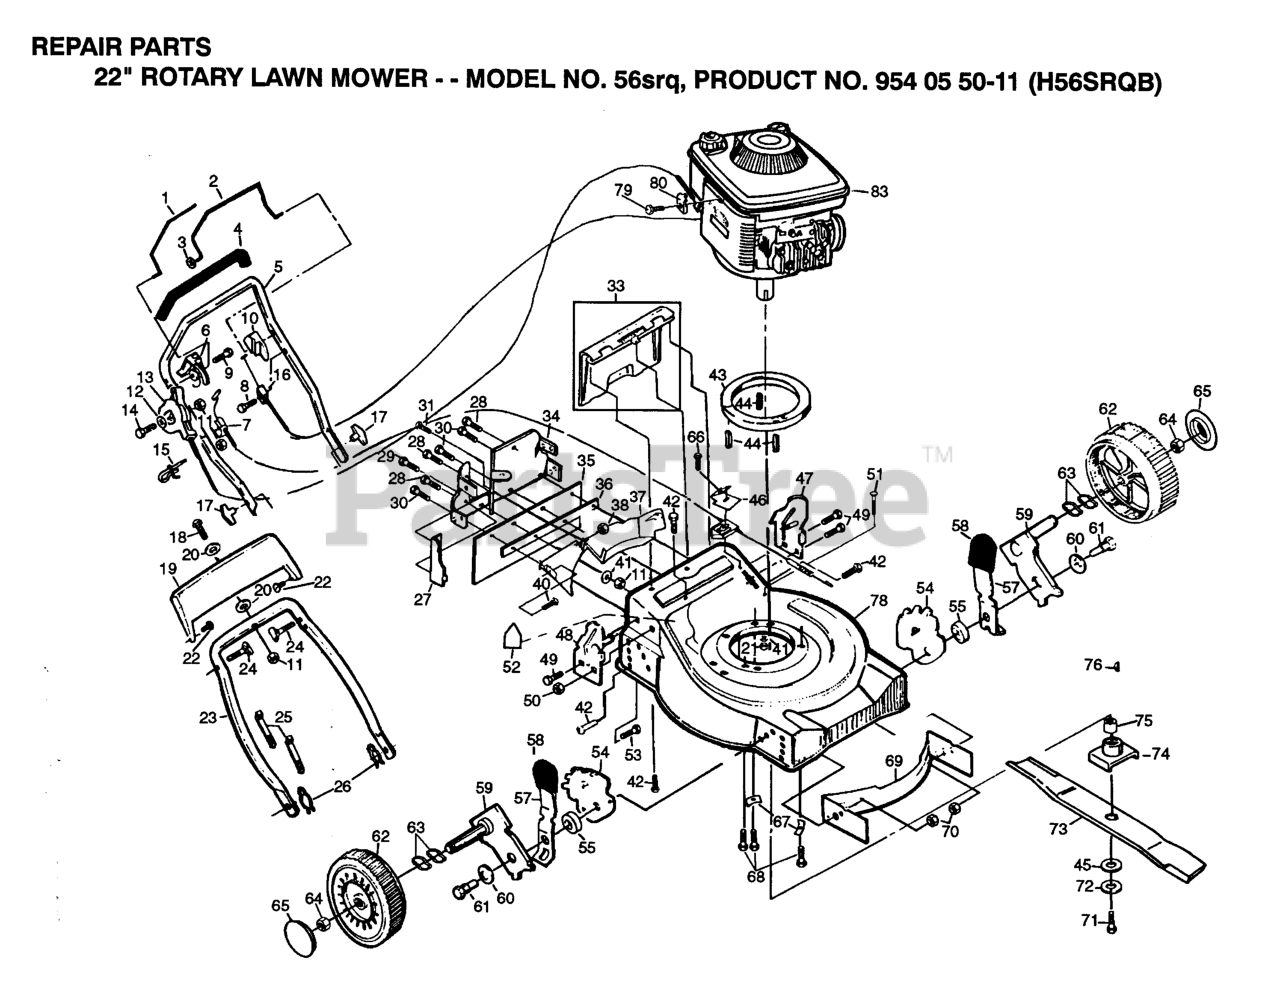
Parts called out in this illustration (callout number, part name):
3	WASHER
4	HANDLE GRIP
5	UPPER HANDLE
6	DR CONT ACTUATOR
8	SCREW, HEX PM
9	SELF-TAPPING SCREW
10	ZONE CONT ACTUATO
11	NUT
13	THROTTLE CONTROL
14	SCREW**
15	ROPE GUIDE
17	KNOB HANDLE
18	SCREW
19	TRIM PLATE
20	WASHER
21	NUT
23	HANDLE, LOWER PM
24	HANDLE BOLT
25	TIE GUIDE
26	HAIRPIN COTTER
28	RIVET BLIND
31	SCREW
33	REAR DOOR KIT
35	SKIRT REAR
37	BAFFLE NLA
43	ENGINE SPACER
44	ENGINE SPACER
45	WASHER,HARDEN
47	BRACKET HANDLE LH
48	BRACKET HANDLE RH
49	SCREW
50	LOCKNUT
52	DECAL HYT
53	Carriage Bolt 5/16-18 x 5/8
54	WHL ADJ BRKT
55	SPACER PM
57	SELECTOR SPRING
59	AXLE ARM AS PM
60	WASHER.BELLEVILLE (3 2 LB)
61	SHOULDER BOLT PM
62	WHL & TIRE ASSEMBLY
63	WAVE WASHER
64	HEX FLANGE LOCKNT
66	SCREW, HEX PM
67	WASHER.ENGINE.BZP
70	LOCKNUT PM
72	LOCKWASHER
73	BLADE 22" PM
74	ADAPTER, BLADE
76	HI PRO KEY PM WSL
79	SCREW.HEX.HEAD.WASHER.10-16
